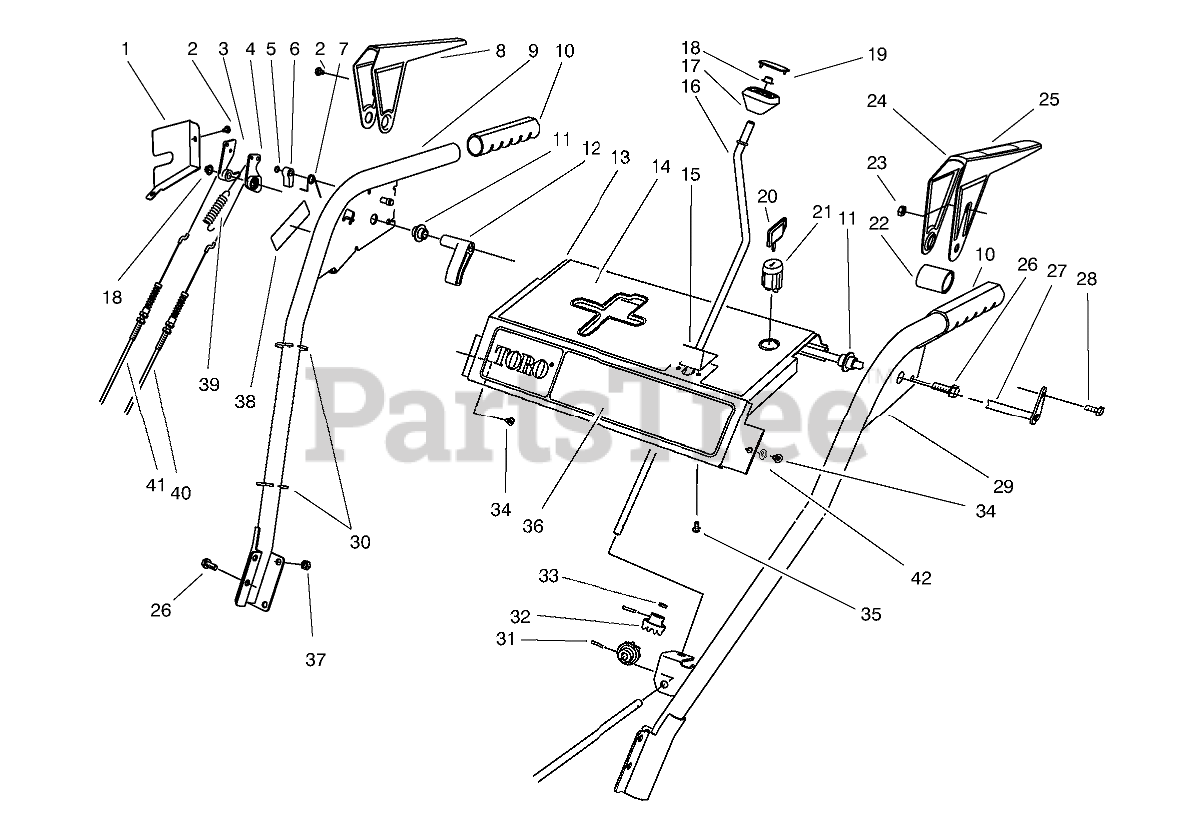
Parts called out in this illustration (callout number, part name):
1	Cover Lever Lock
2	SCREW-HH
3	TANG-LOCKING
4	CAM-RELEASE
5	E-RING-RETAINER
6	LATCH-LOCKING
7	SPRING-TORSION
8	Lever-Impeller
9	Handle-R.H.
10	GRIP-HANDLE
11	BUSHING-LEVER
12	LEVER-TRIP
13	Panel-Control
14	DECAL-TOP PANEL
15	PLATE-GUIDE
16	CRANK-ROD, CHUTE
17	KNOB-CONTROL, CHUTE
18	RETAINER-PUSH ON
19	COVER-KNOB
20	KEY-IGNITION
21	SWITCH
22	SPACER-LEVER, TRACTION
23	NUT-LOCK, NI
24	Lever-Traction
25	DECAL-LEVER
26	SCREW-HWHTF
27	CROSS ROD ASM
28	SCREW-HWH
29	Handle-L.H.
30	TIE-CABLE
31	PIN-SPRING
32	GEAR-UNIVERSAL
33	WASHER-RUBBER
34	SCREW-HWHTF
35	SCREW
36	DECAL-FRONT PANEL (824)
37	NUT-LOCK, NI
38	DECAL-WARNING
39	SPRING-EXTENSION
40	CABLE-TRACTION
41	CABLE-IMPELLER
42	WASHER-FLAT
